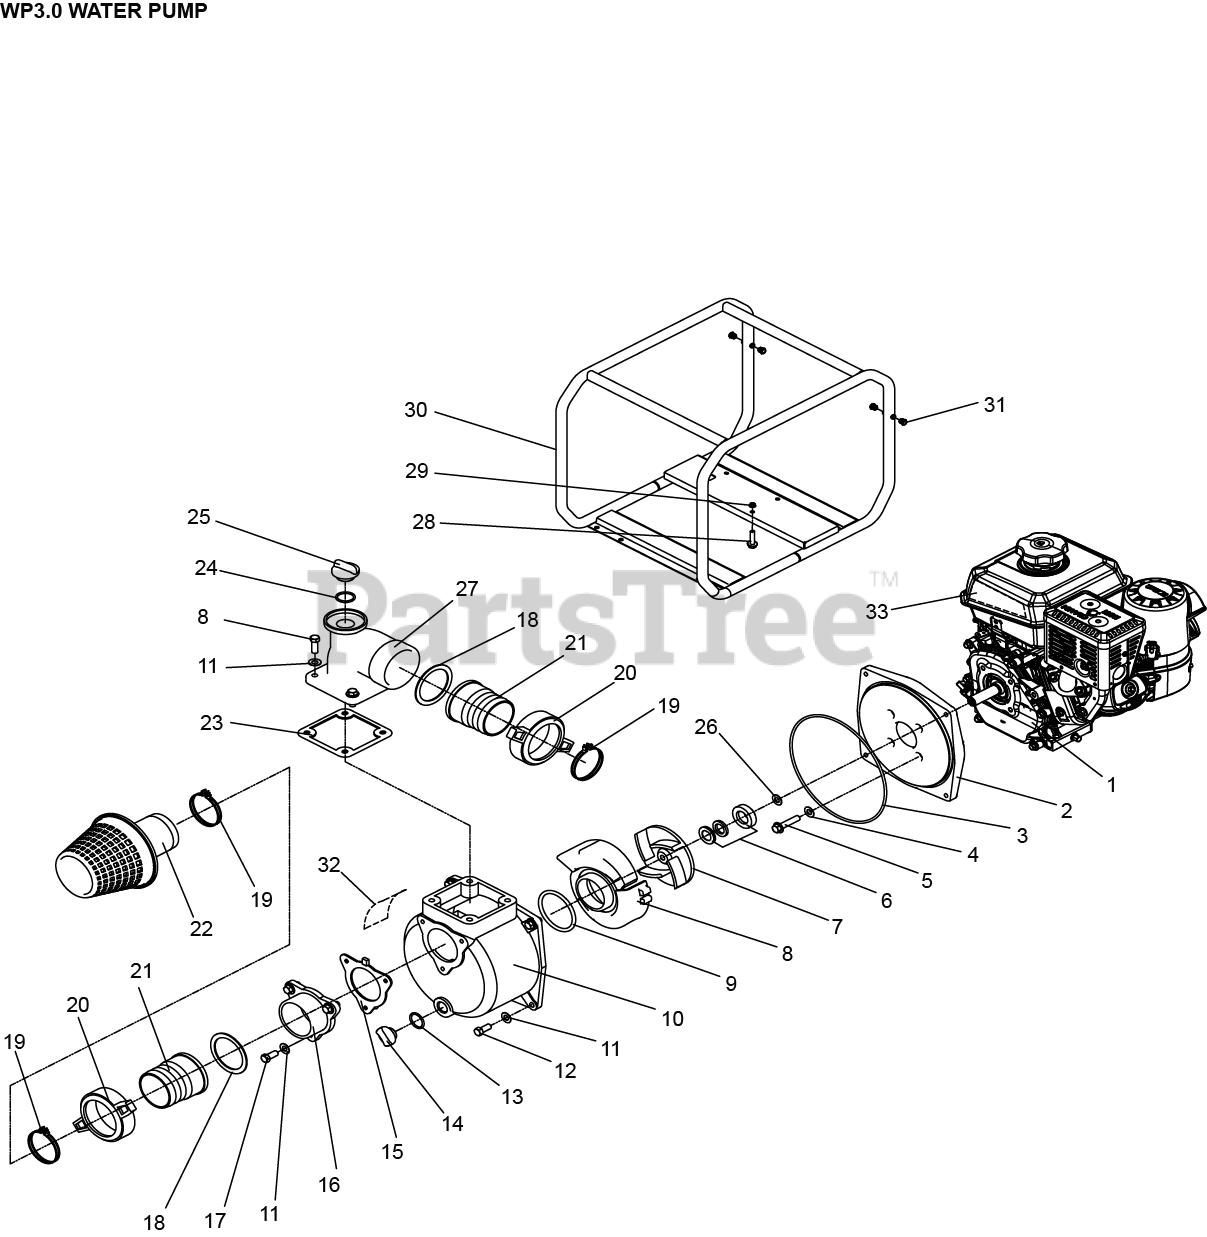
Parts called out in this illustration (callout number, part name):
1	CH270 E3 MARKETING BASIC
2	ADAPTER, PUMP COVER WP3.0
3	O-RING 226 WP3.0
4	WASHER 8 TP3.0
5	BOLT 5/16-24UNF-2A (L=60)
6	SEAL, MECHANICAL WP3.0
7	PUMP ASSEMBLY, IMPELLER WP3.0
8	HOUSING, DIFFUSOR WP3.0
9	O-RING 85 WP3.0
10	BODY, PUMP WP3.0
11	WASHER 10
12	BOLT M10X25
13	O-RING 30*3.1 TP3.0
14	PLUG TP3.0
15	GASKET WP3.0
16	FLANGE, SUCTION WP3.0
17	BOLT M10X20
18	GASKET, RUBBER PACKING TP3.0
19	CLAMP TP3.0
20	NUT, JOINT GRIP TP3.0
21	FITTING, PIPE JOINT TP3.0
22	FILTER NET WP3.0
23	GASKET, RUBBER PAD WP3.0
24	O-RING 38*3 WP3.0
25	PLUG WP3.0
26	SHIM, ADJUSTING
27	ELBOW, OUTLET SEAT WP3.0
28	BOLT M8X40 GB 5789
29	NUT, JOINT GRIP WP2.0
30	FRAME ASSEMBLY WP3.0
31	PLUG, END CAP
32	Performance Label
33	Brand Label
